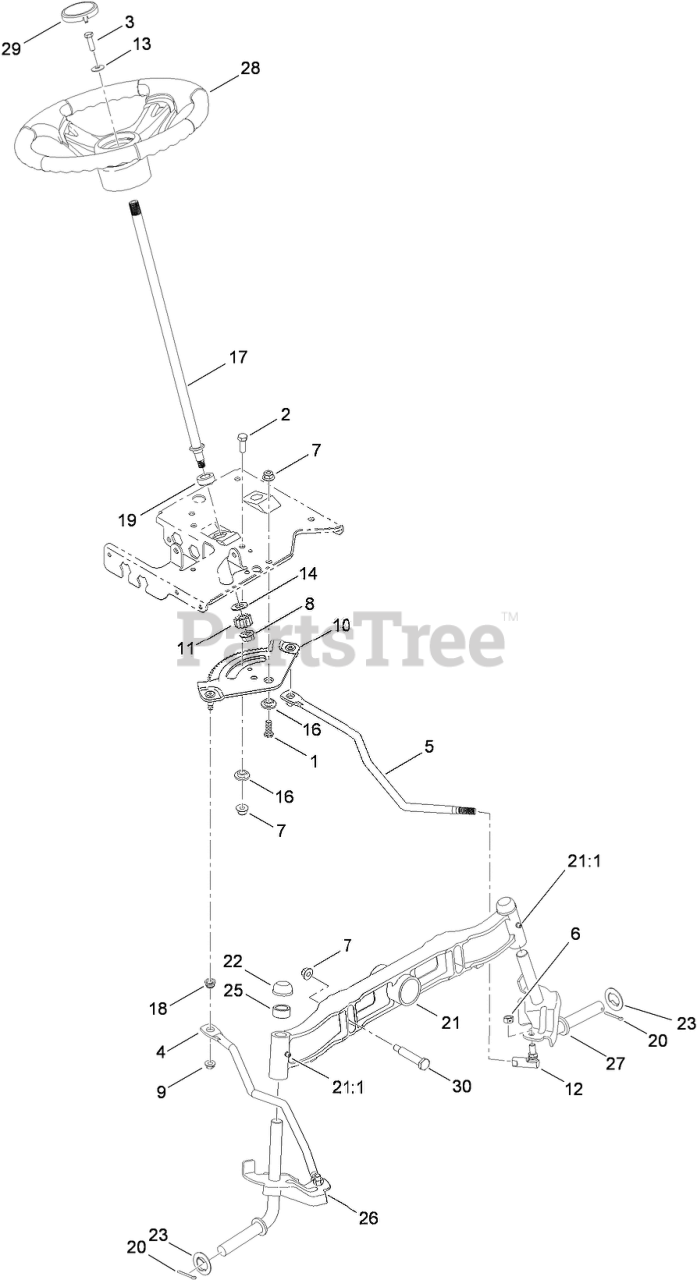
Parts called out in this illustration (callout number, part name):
1	SCREW-HH
2	SCREW-HH
3	SCREW-HH
4	LINK-DRAG, RH
5	LINK-DRAG, LH
6	NUT-HEX, LOCK
7	NUT-LOCK, FLANGE
8	NUT-LOCK, FLANGE
9	NUT-LOCK, FLANGE
10	GEAR-STEERING
11	GEAR-PINION, STEERING
12	BALL JOINT ASM
13	WASHER-FLAT
14	WASHER-FLAT
16	SPACER-SHOULDER
17	SHAFT-STEERING
18	BUSHING
19	BEARING-FLANGE, HEX
20	PIN-COTTER
21	PIVOT-AXLE, CAST IRON
21:1	FITTING-GREASE
23	WASHER-FLAT
25	SPACER
26	RH AXLE ASM
27	LH AXLE ASM
28	3 SPOKE WHEEL STEERING ASM
29	CAP-WHEEL, STEERING
30	BOLT-SHOULDER
